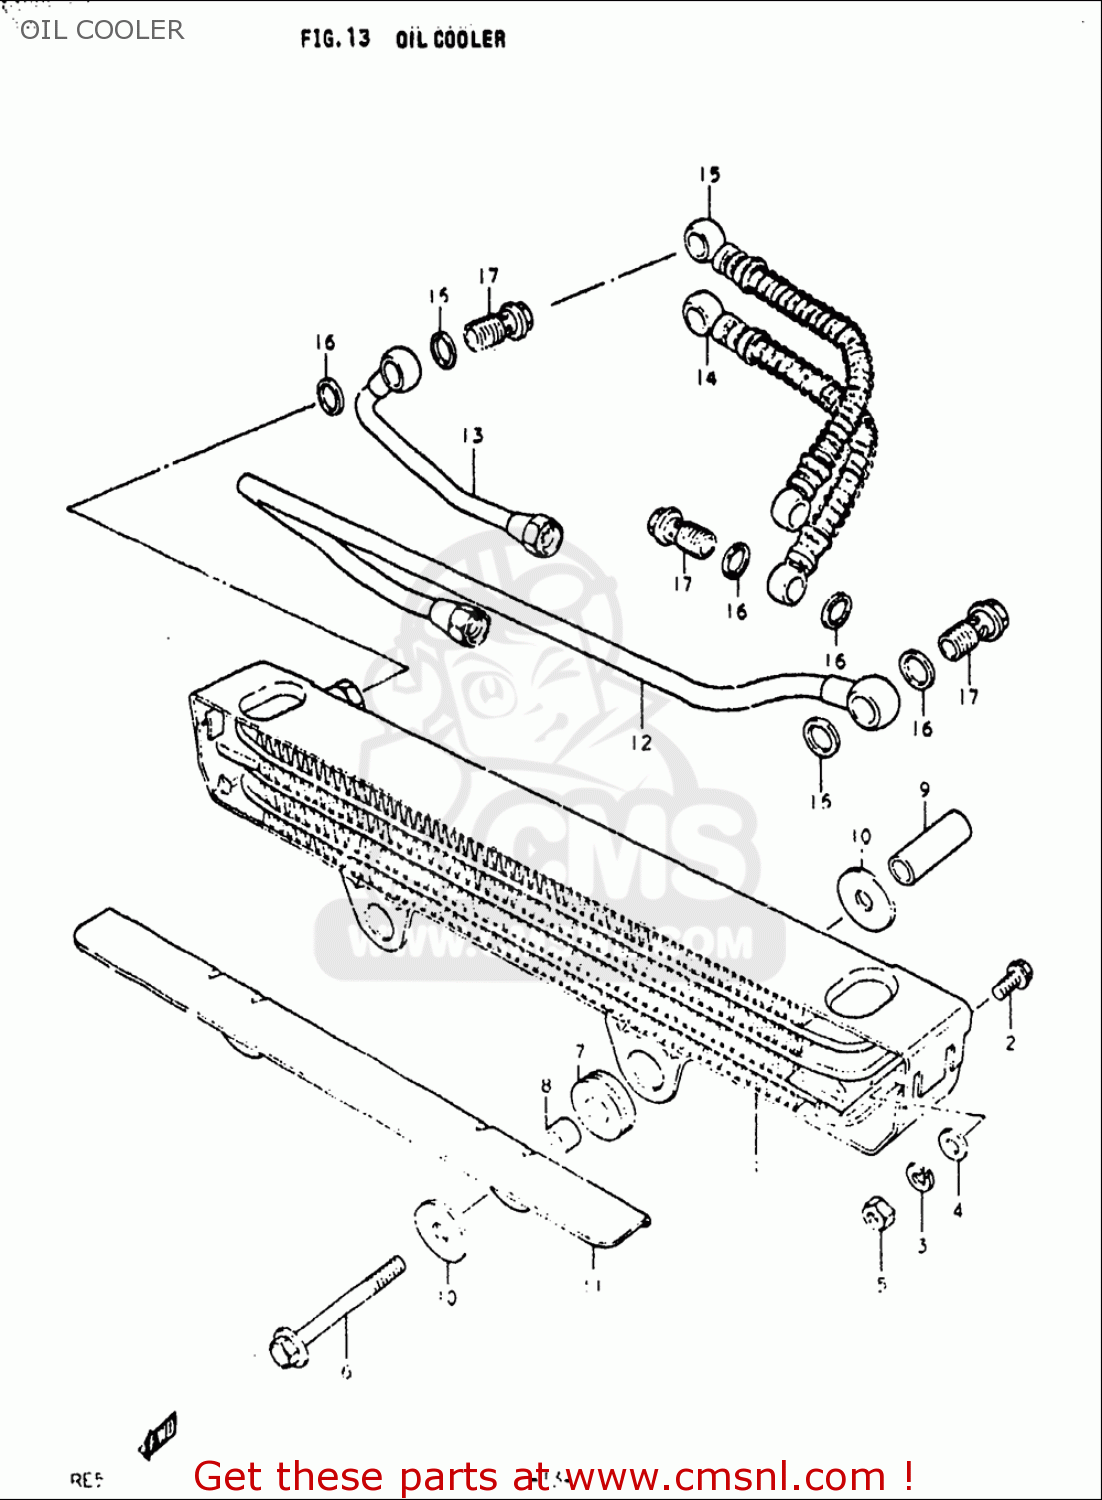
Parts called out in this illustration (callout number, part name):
2	BOLT
3	WASHER,LOCK
4	WASHER
5	NUT
6	BOLT
8	SPACER,8.5X14X9
